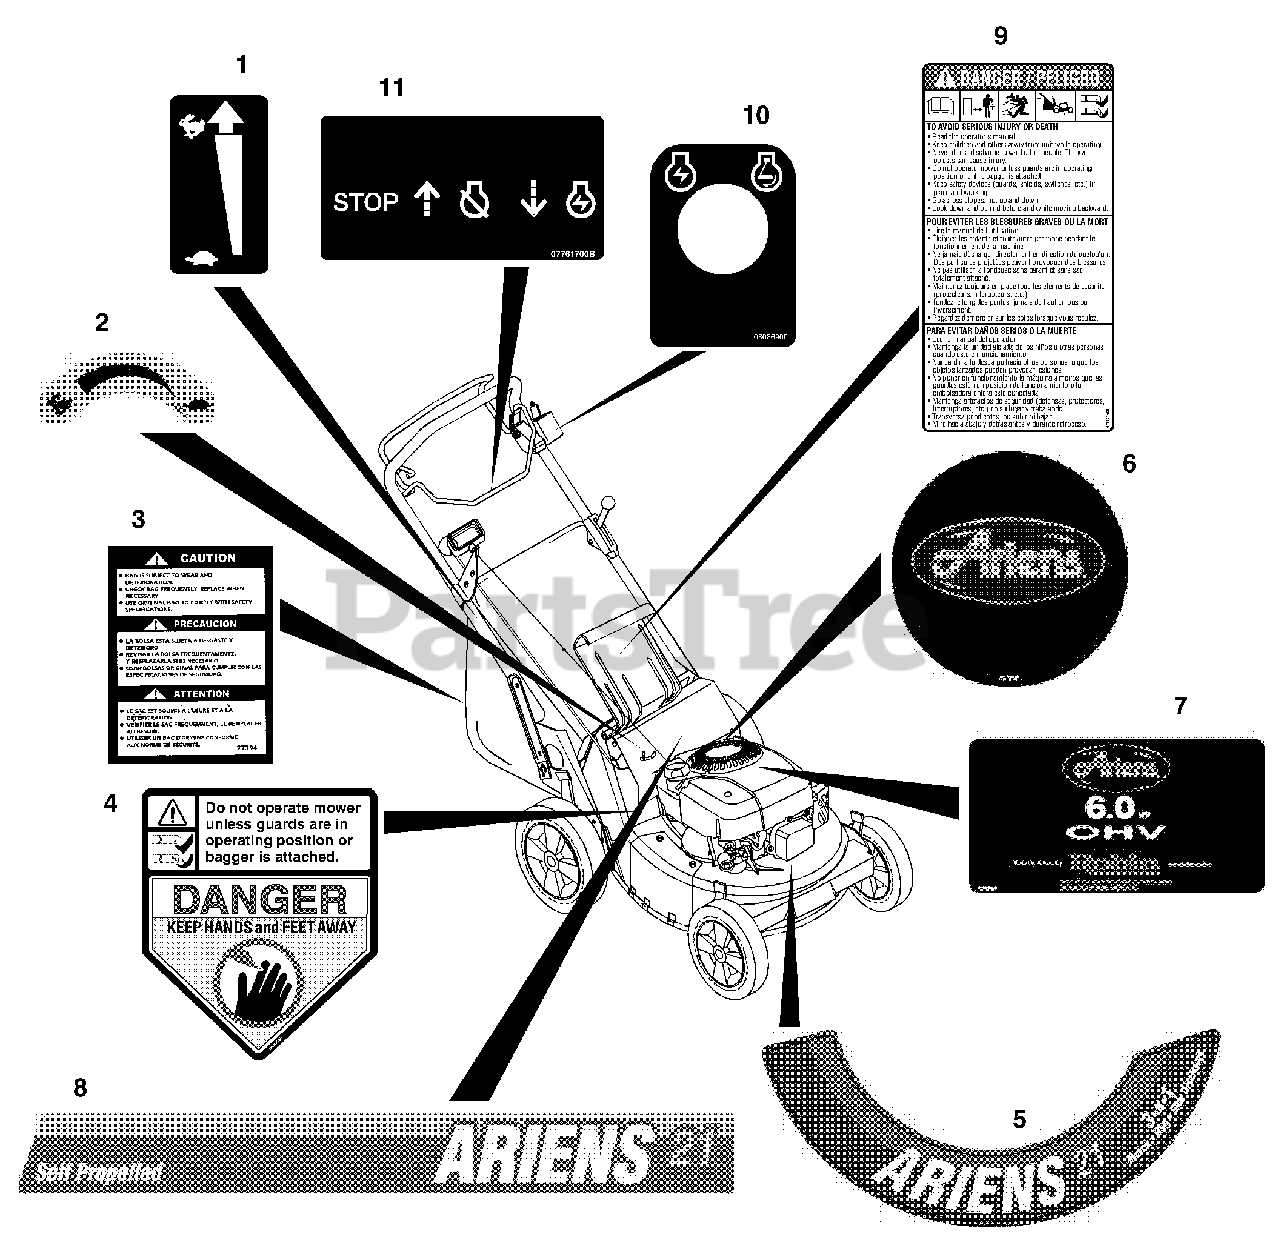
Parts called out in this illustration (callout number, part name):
1	DECAL-SPEED CONTROL
2	DECAL, TURTLE & RABBIT
3	LABEL - BAGGER 21"
4	DECAL, CPSC DANGER
5	DECAL, ARIENS DECK
6	DECAL, RD ARIENS ROBIN ENG RCL
7	DECAL, 6.0HP OHV ARIENS & ROB.
8	DECAL, DRIVE COVER SP
9	DECAL, BILINGUAL DANGER
10	DECAL, KEYSWITCH LM 2-POS
11	DECAL - ENGINE CONTROL
